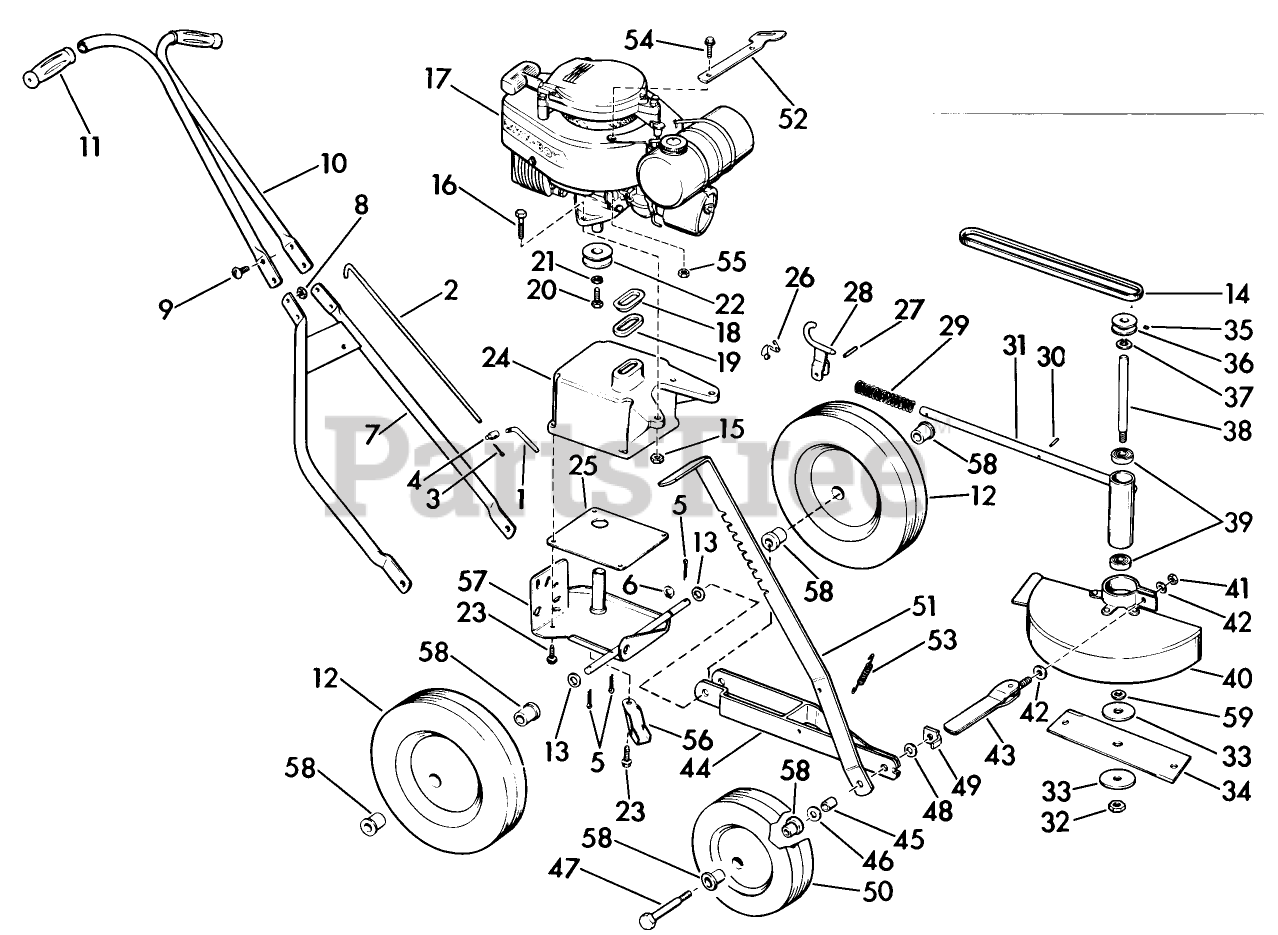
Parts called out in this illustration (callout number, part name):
8	STOP NUT
17	Engine-C-71
21	WASHER, LOCK
34	Blade-9"
44	Wheel Bracket and Spacer Assy.
48	WASHER, LOCK
